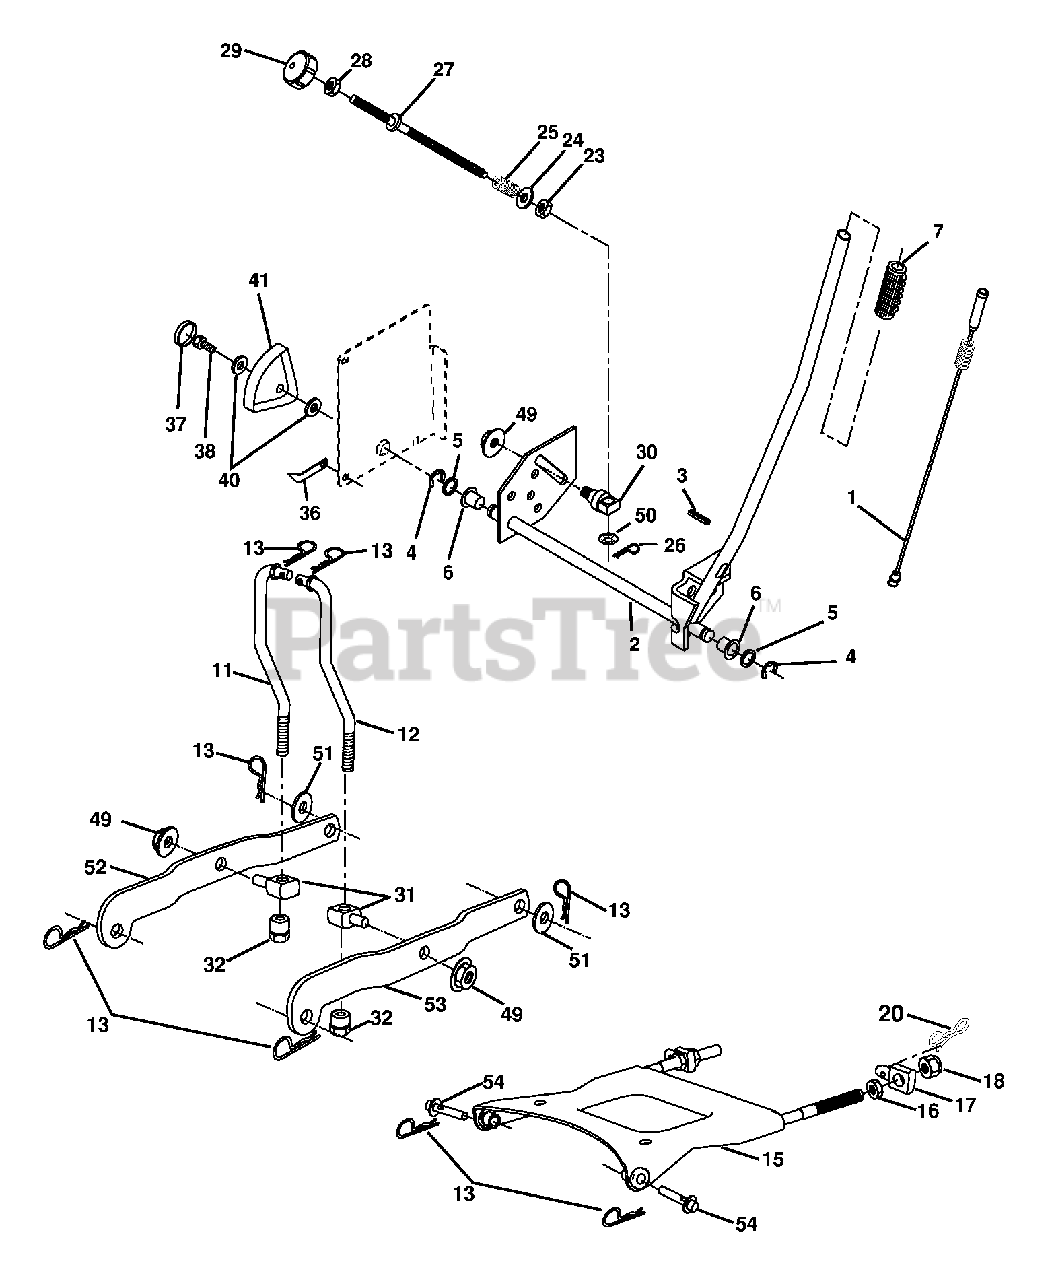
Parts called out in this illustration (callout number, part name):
1	Plunger Asm.
2	Shaft Asm Lift RH w/Inf
3	Pin Groove
4	E Ring #5133-62
5	Washer 21/32 x 1 x 21 Ga.
6	Bearing Nylon Blk 629 Id
7	Grip Handle
11	Link Lift LH
12	Link Lift RH
13	Retainer Spring
15	Plate Asm. Suspension Front
16	Nut Jam Hex 1/2-13 unc
17	Trunnion Front Susp.
18	Nut Lock w/Wsh 1/2-13 unc
20	Pin Cotter 7/16 Bow Tie Lock
23	Nut Special
24	Washer 13/32 x 5/8 x 16 Ga.
25	Spring
26	Retainer Clip
27	Rod Adj Lift
28	Nut Hex Jam 3/8-16 unc
29	Knob Inf 3/8-16 unc Blk W/sym
30	Trunnion Infin Height
31	Trunnion Susp. Arm
32	Nut Lift Link 7/16-20
36	Pointer Height Indicator
37	Plug Hole Blk 1.485/1.515 Dia.
38	Screw 5/16-18 x 1
40	Washer 11/32 x 1-1/2 10 Ga.
41	Indicator Height STLT
49	Nut Hex Flange Lock
50	Nut PUsh Phos & Oil
51	Washer 17/32 x 7/8 x 16 Ga.
52	Arm Susp. Rear LH
53	Arm Susp. Rear RH
54	Pin
